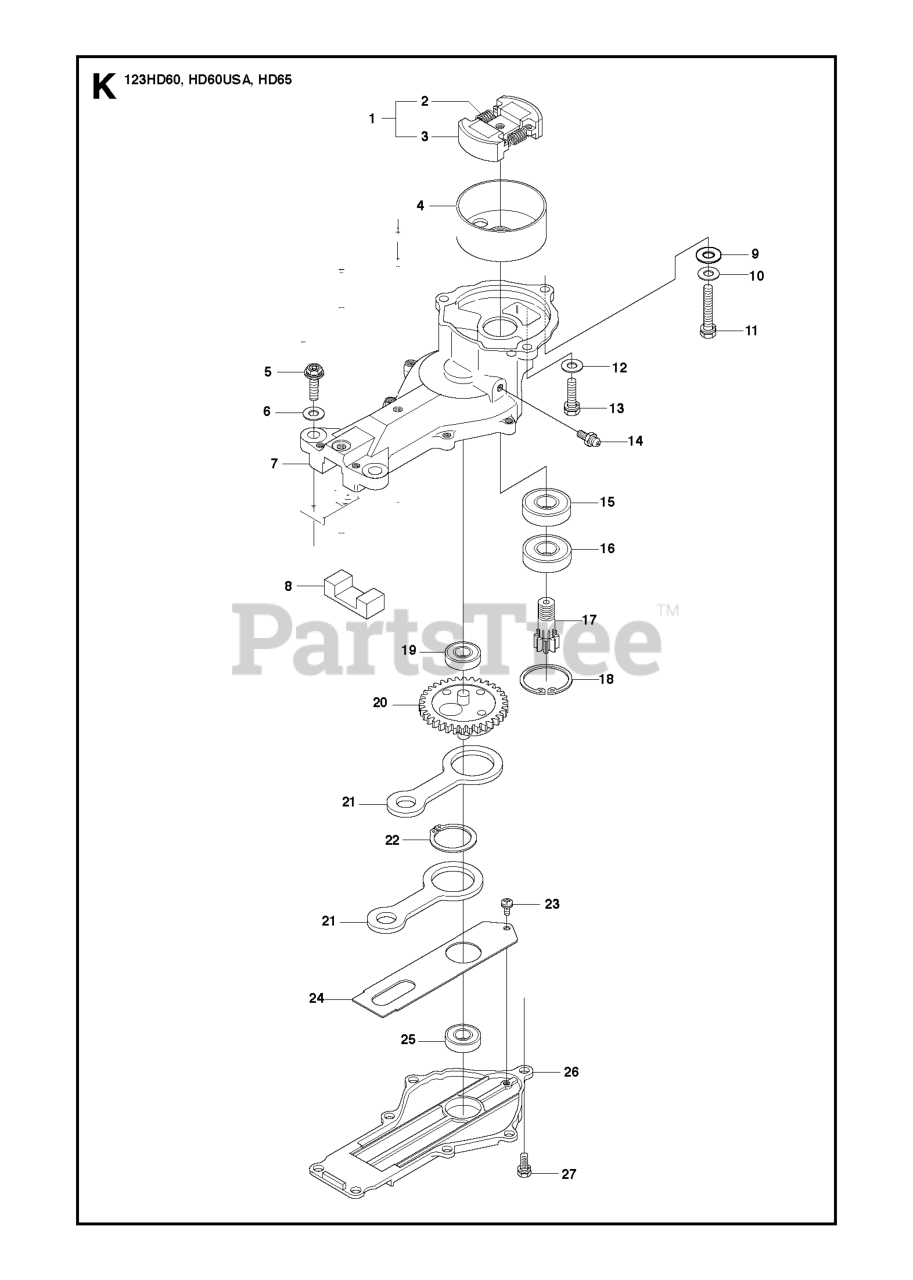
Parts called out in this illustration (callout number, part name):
4	CLUTCH DRUM
7	GEAR HOUSING
8	GREASE FILTER
9	WASHER - M6
11	BOLT FLANGE
14	GREASE FITTING
18	RETAINING RING
20	CRANK GEAR
22	RETAINING RING
